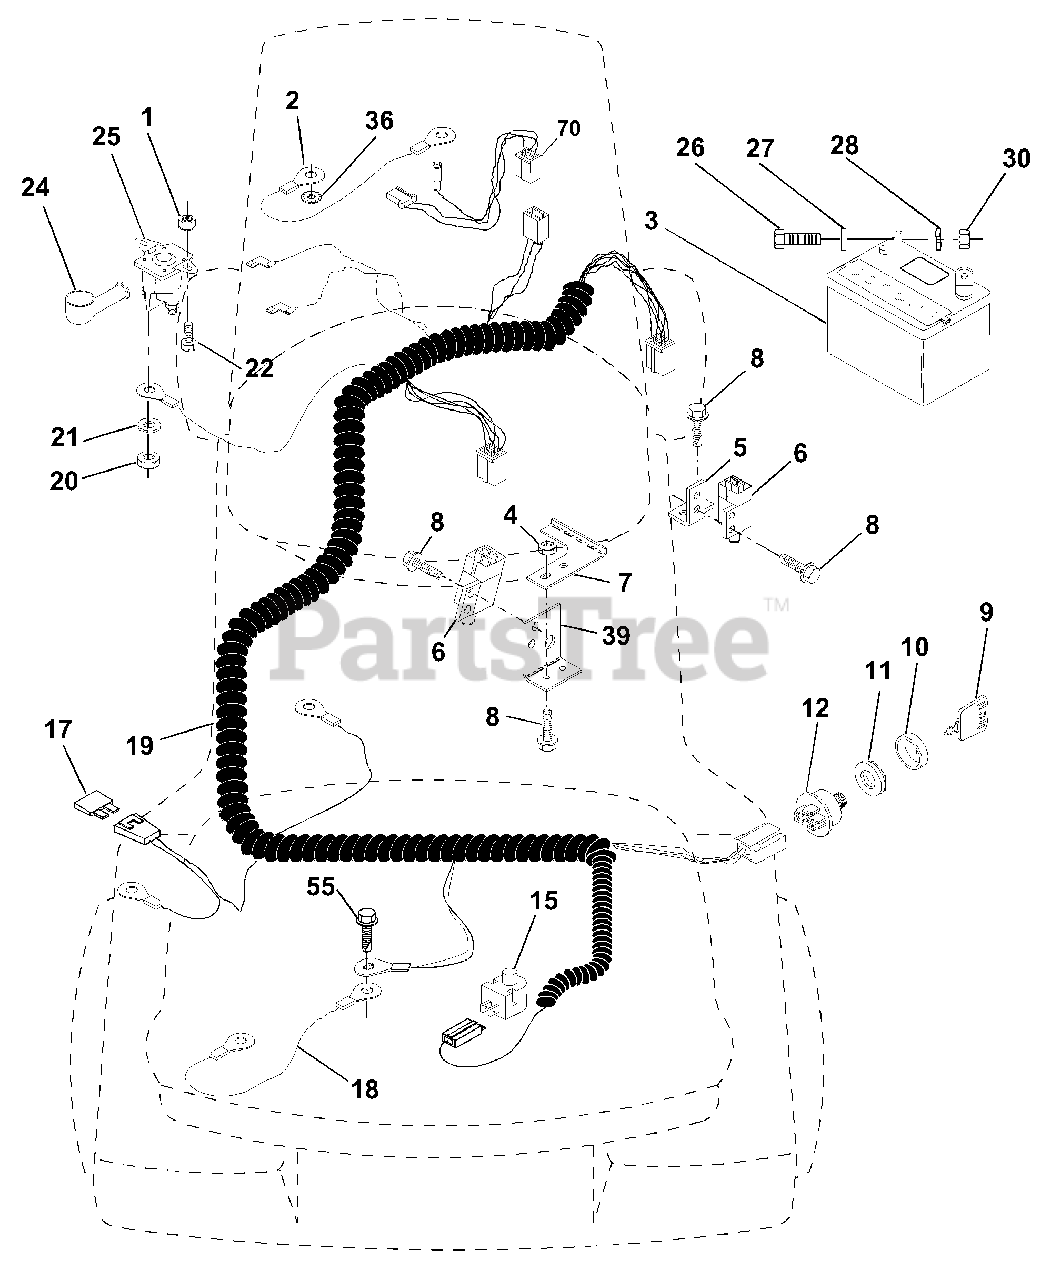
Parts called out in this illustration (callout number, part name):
1	Nut, Hex Keps 1/4-20
2	Assembly, Cable
3	Battery
4	Nut, Lock #10-24 UNC
5	Bracket, Switch
6	Switch, Interlock (4-terminal)
7	Keeper, Actuator
8	Screw, Hex Hd. Tap #10-24 x 1/2
9	Key, Steel Delta
10	Cover, Key Ignition
11	Nut, Ignition
12	Switch, Ignition
15	Switch, Plunger
18	Assembly, Cable
19	Harness, Ignition
20	Nut, Hex Jam 1/4-20
21	Washer, Lock 1/4
22	Bolt, Fin. Hex 1/4-20 UNC x 1/2 Gr. 5
24	Cover, Terminal
25	Solenoid
26	Bolt, Hex Hd. 1/4-20 UNC x 3/4
27	Washer 9/32 x 5/8 x 16
28	Washer, Lock 1/4
30	Nut, Fin. Hex 1/4-20 UNC
36	Washer Lock Inter. Tooth 1/4
39	Bracket Switch Clutch
55	Screw Thdrol 5/16-18 x 1/2
70	Harness Engine
